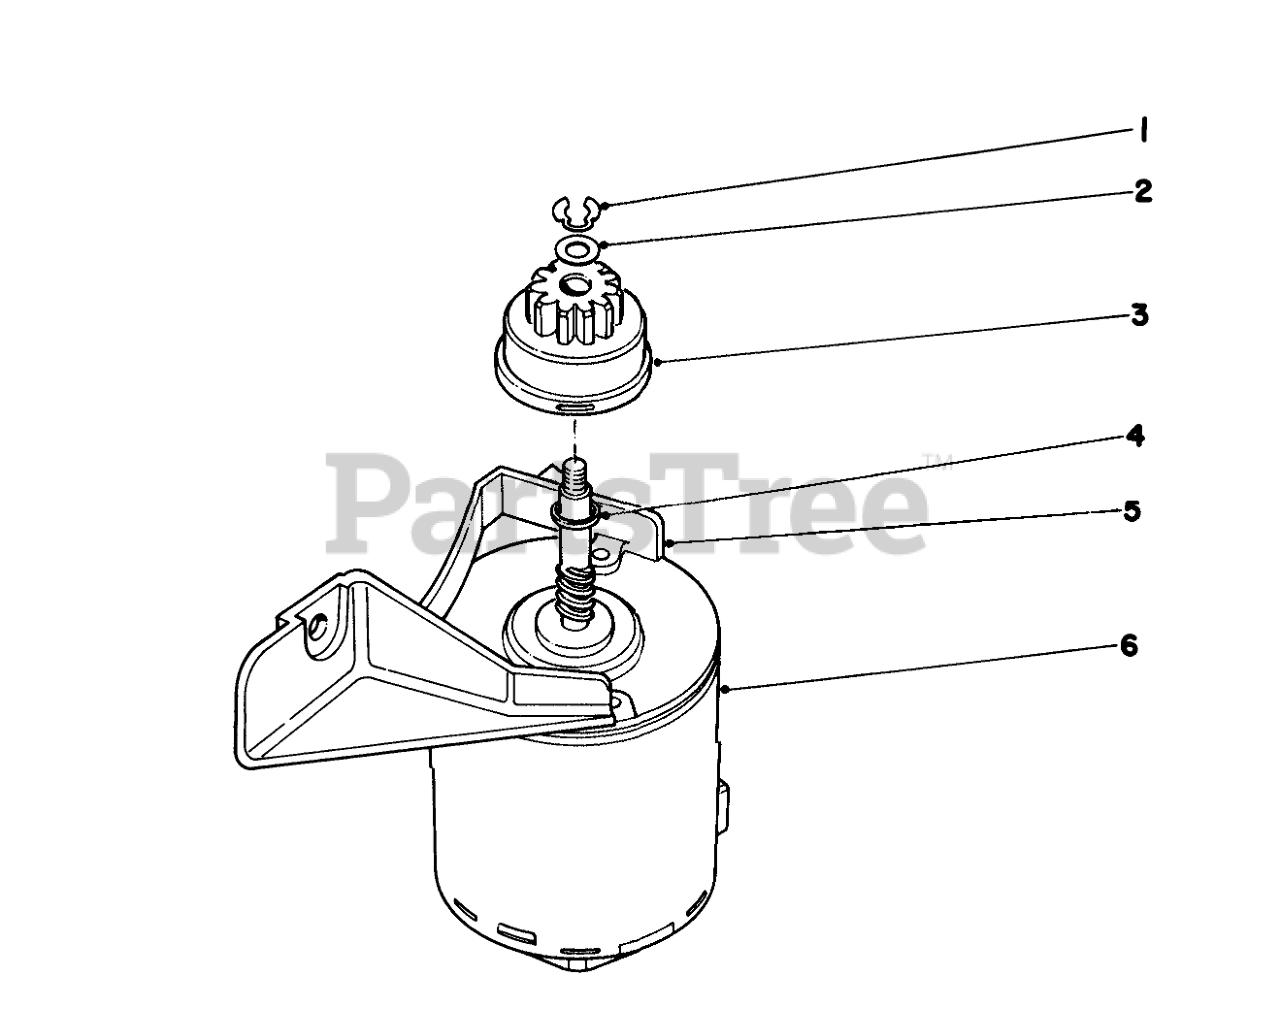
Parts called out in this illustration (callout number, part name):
1	RING-RETAINING
2	WASHER
3	PINION ASM
4	Spacer
5	Mounting Bracket
6	Starter Motor
